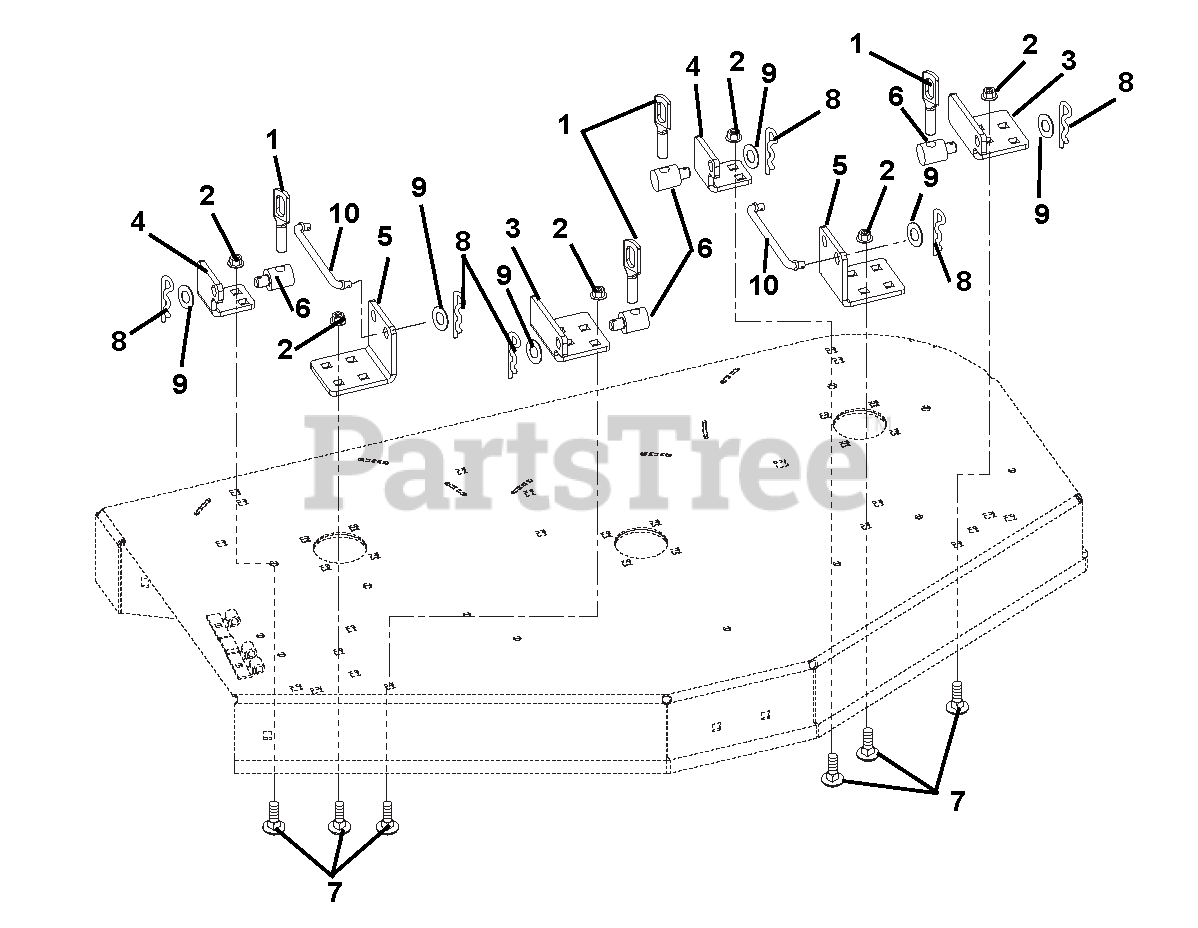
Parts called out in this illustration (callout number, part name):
1	DECK LINK
2	@NUT-LK-NYL-FLG .38-16 YWZC
3	BRACKET, FRONT MOUNT
4	BRACKET, REAR MOUNT
5	BRACKET, STABILIZER
6	TRUNNION-.50
7	@BLT-RDHDSQNK .38-16X1.00 G5YZ
8	PIN, HAIR, EXT - #16 YWZC
9	WSHR-FL-STL.511X1.441X.125 YWZ
10	ROD,DRAG LINK
